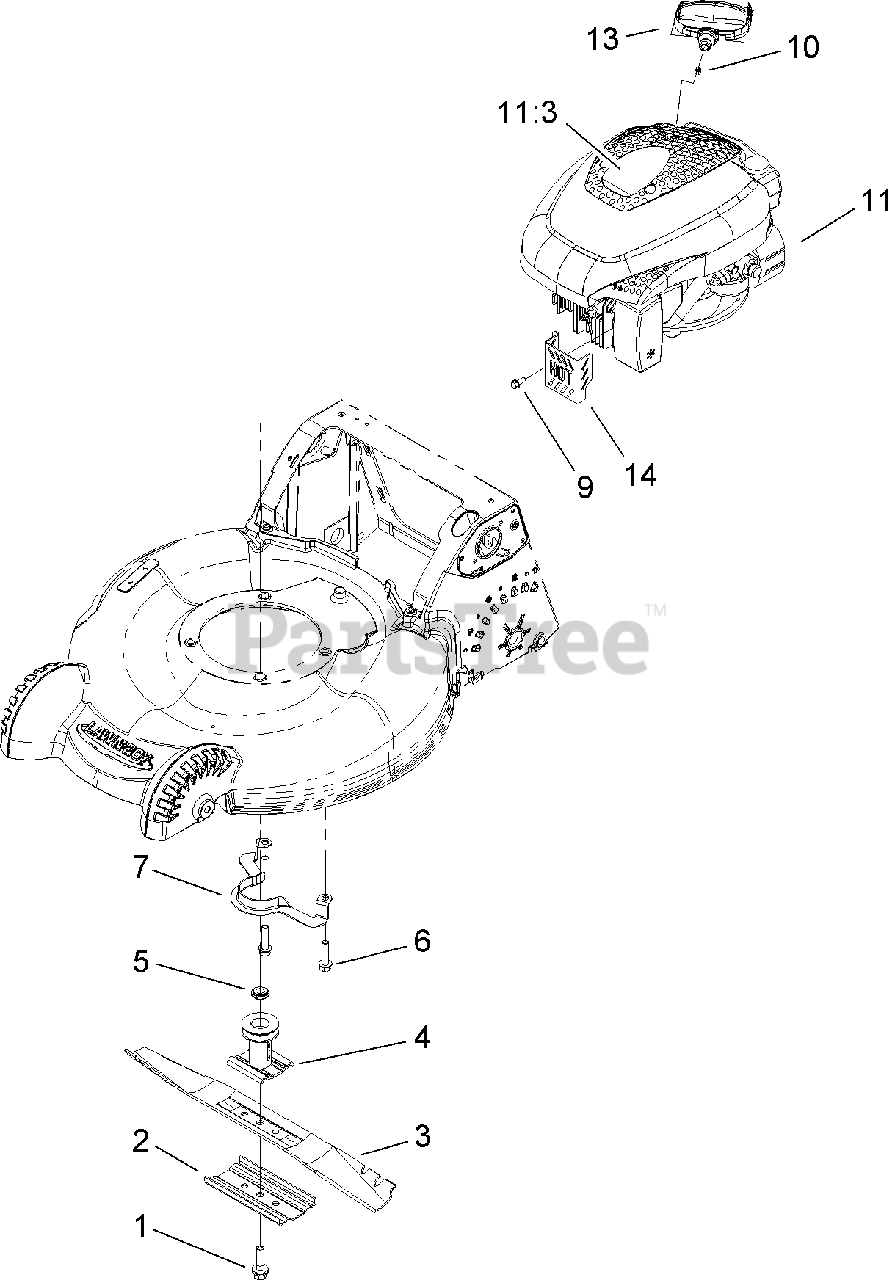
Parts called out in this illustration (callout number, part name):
1	BOLT-BLADE
2	SUPPORT-BLADE
3	BLADE-21 INCH
4	BLADE DRIVER ASM
5	Spacer-Driver
6	SCREW-HWH
9	SCREW-HWH
10	STOP-ROPE
11:3	DECAL-ENGINE
13	HANDLE-RECOIL
14	GUARD-MUFFLER
